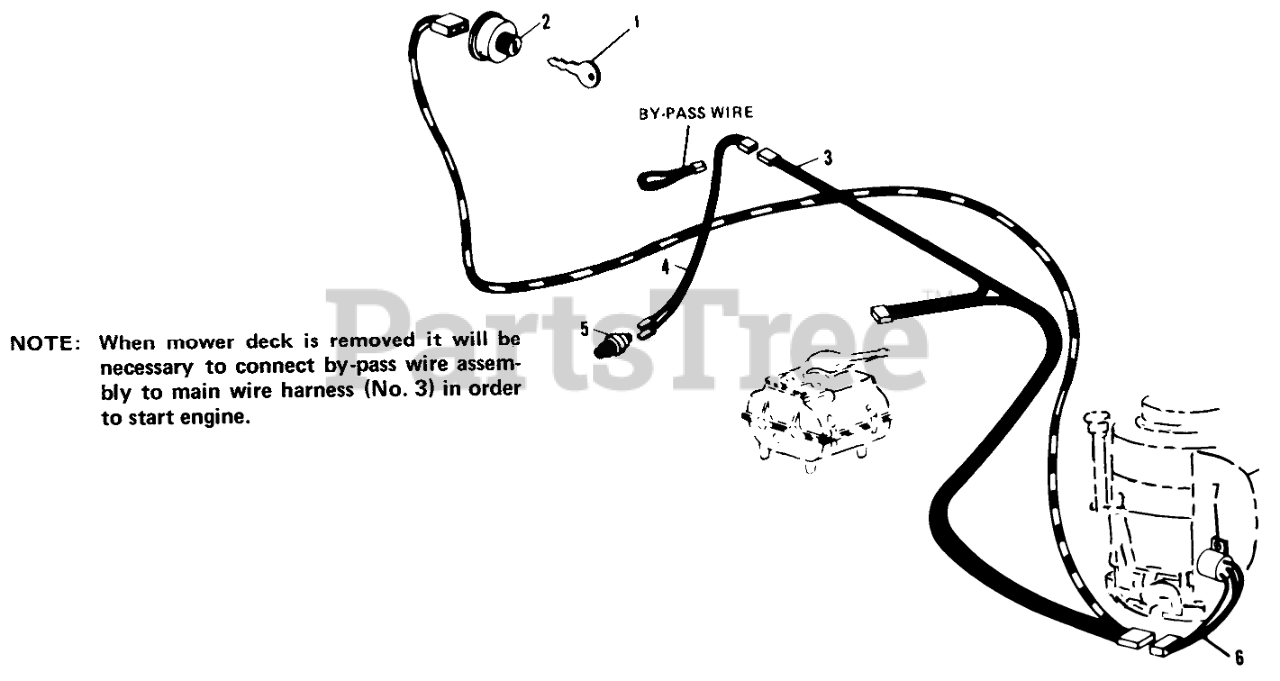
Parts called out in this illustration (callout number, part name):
1	Key, Ignition
2	Ignition Switch
3	Wire Harness Assy.
4	Wire Assy, Deck Switch
5	Safety Switch
6	Cup-Starter
7	Screw, No.10-32 x 1/2 In.
